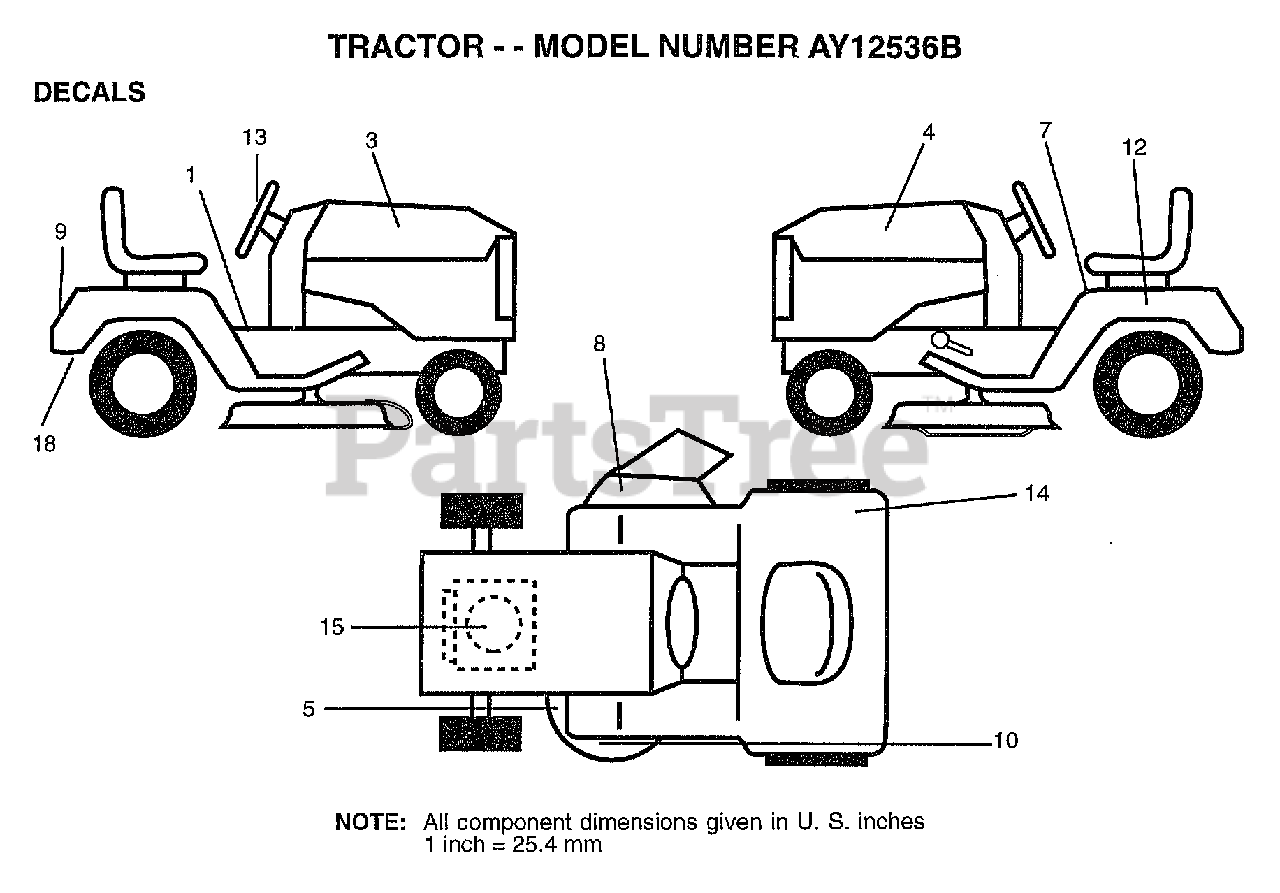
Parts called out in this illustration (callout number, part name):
1	DECAL.OP.INST.SYM
3	"DECAL,HOOD.RH"
4	"DECAL,HOOD,LH"
5	DECAL.V.BELT
7	DECAL.READ.O.MANU
8	DECAL.DANGER.CUTF
9	"DECAL,FENDER"
10	DECAL DECK WIZ +
12	DECAL.BTRY.DANGER
13	"DECAL,INSERT"
15	DECAL, ENGINE
18	DECAL.EURO.ST.CE.
